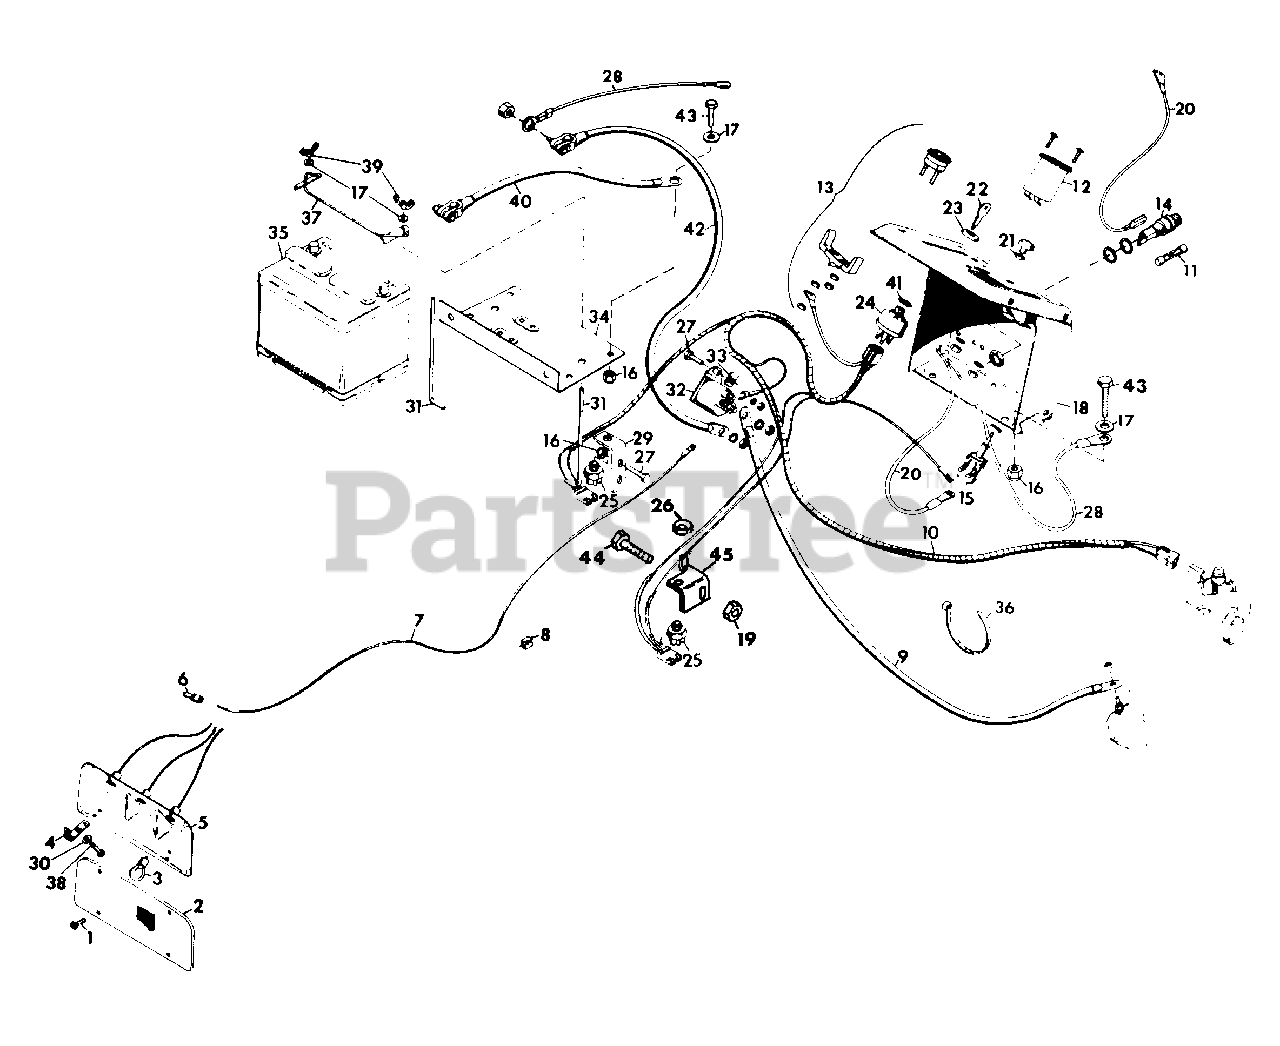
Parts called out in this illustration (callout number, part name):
1	SCREW, MACH, 10-24X.50 PAN HD C-RECESS
2	PANEL, FRONT LIGHT
3	LAMP, NO. 1073
4	CLIP, LIGHT MTG.
5	ASSEMBLY, LAMP REFLECTOR
6	NUT, WIRE
7	WIRE, HEADLIGHT
8	CLIP, WIRE
9	CABLE, STARTER
10	HARNESS, WIRING KOHLER TWIN
11	FUSE, 30 AMP AGC-30
12	HOURMETER
13	GAUGE, AMMETER
14	FUSE, PANEL
15	SWITCH, LIGHT
16	NUT, LOCK 1/4-20
17	WASHER, FLAT .281X.625X.065
18	PANEL, INSTRUMENT W/AMMETER & HOURMETER
19	NUT, LOCK 3/8-16
20	WIRE, HOURMETER
21	NUT, SPECIAL, LIGHT SWITCH
22	KEY, IGNITION SWITCH
23	NUT, JAM 9/16-24
24	SWITCH, IGNITION
25	SWITCH, INTERLOCK
26	NUT, STAMPED 9/16-18
27	BOLT, HEX 1/4-20X.625
28	WIRE, INSTRUMENT PANEL
29	BRACKET, SWITCH
30	WASHER, FLAT .188X.562X.049
31	HOOK, BATTERY
32	SWITCH, MAGNETIC
33	NUT, SPEED 1/4-20
34	TRAY, BATTERY
35	BATTERY, 12V
36	TIE, CABLE
37	BRACKET, BATTERY HOLD DOWN
38	SCREW MACH 10-24X.75 PAN HD C-RECESS
39	NUT, WING 1/4-20 WASHER INSERT
40	CABLE, NEGATIVE BATTERY
41	WASHER, LOCK 9/16 INT. TOOTH
42	CABLE, BATT TO MAGNETIC SWITCH
43	BOLT, HEX 1/4-20X.875
44	BOLT, HEX 3/8-16X1.25
45	BRACKET, INTERLOCK SWITCH
NS	WASHER, LOCK 1/4 EXT TOOTH TYPE A
NS	BOOT, BATTERY CABLE
